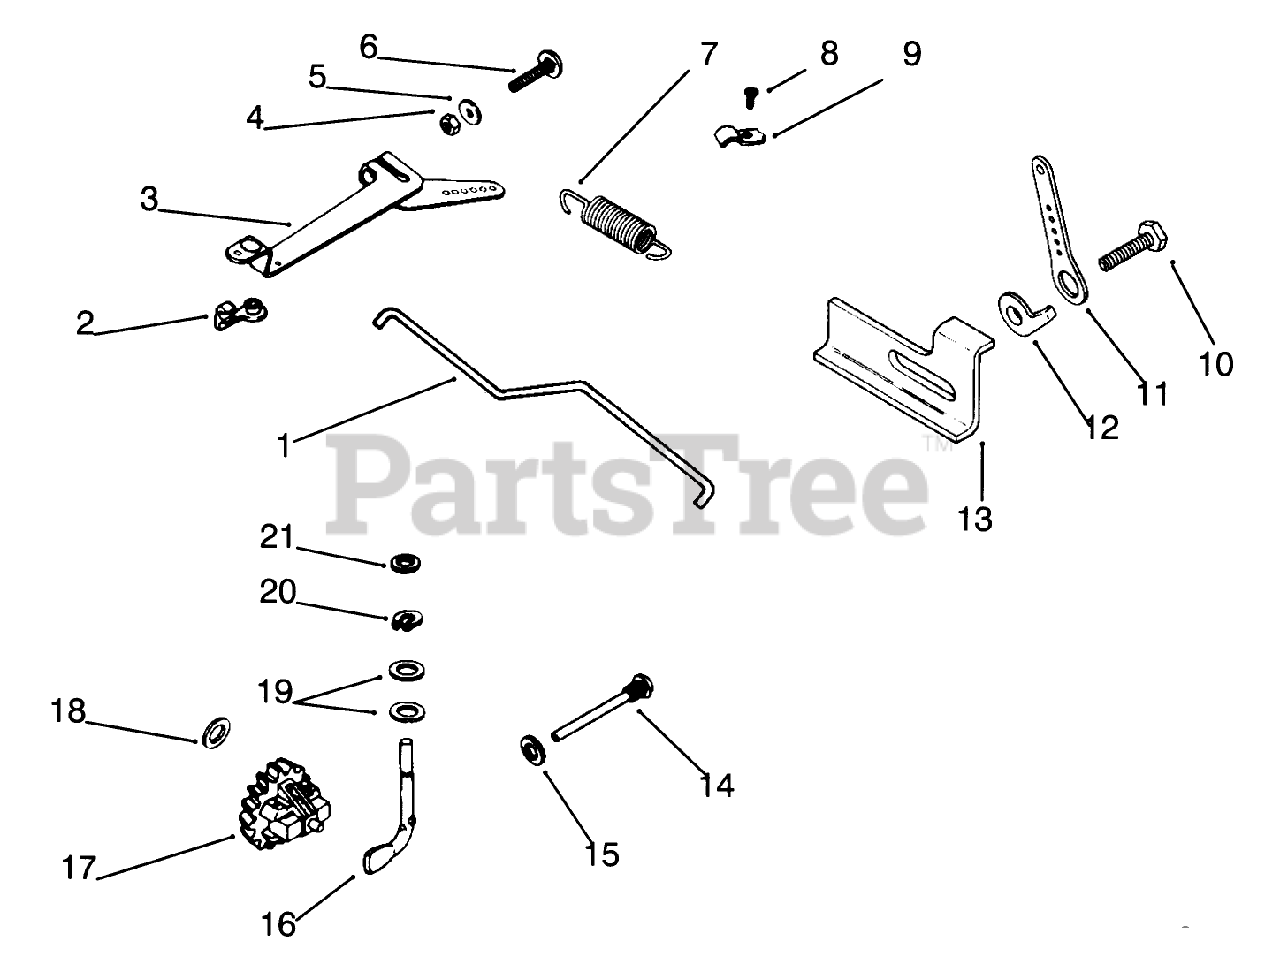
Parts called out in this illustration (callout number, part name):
1	Kit-Governor Linkage (Incl. Ref. #2)
2	Bushing
3	Arm-Governor
5	Washer
6	Screw-Round Hd.
7	Spring-Governor
8	Clip
9	Screw
10	Screw
11	Lever-Speed Control
12	Stop-Govenor
13	Stop-High Speed
14	Pin-GovemorStop
15	Washer
16	Shaft-Govenor
17	Governor Gear
18	Washer
19	Washer
20	Retainer-Governor
21	Washer
